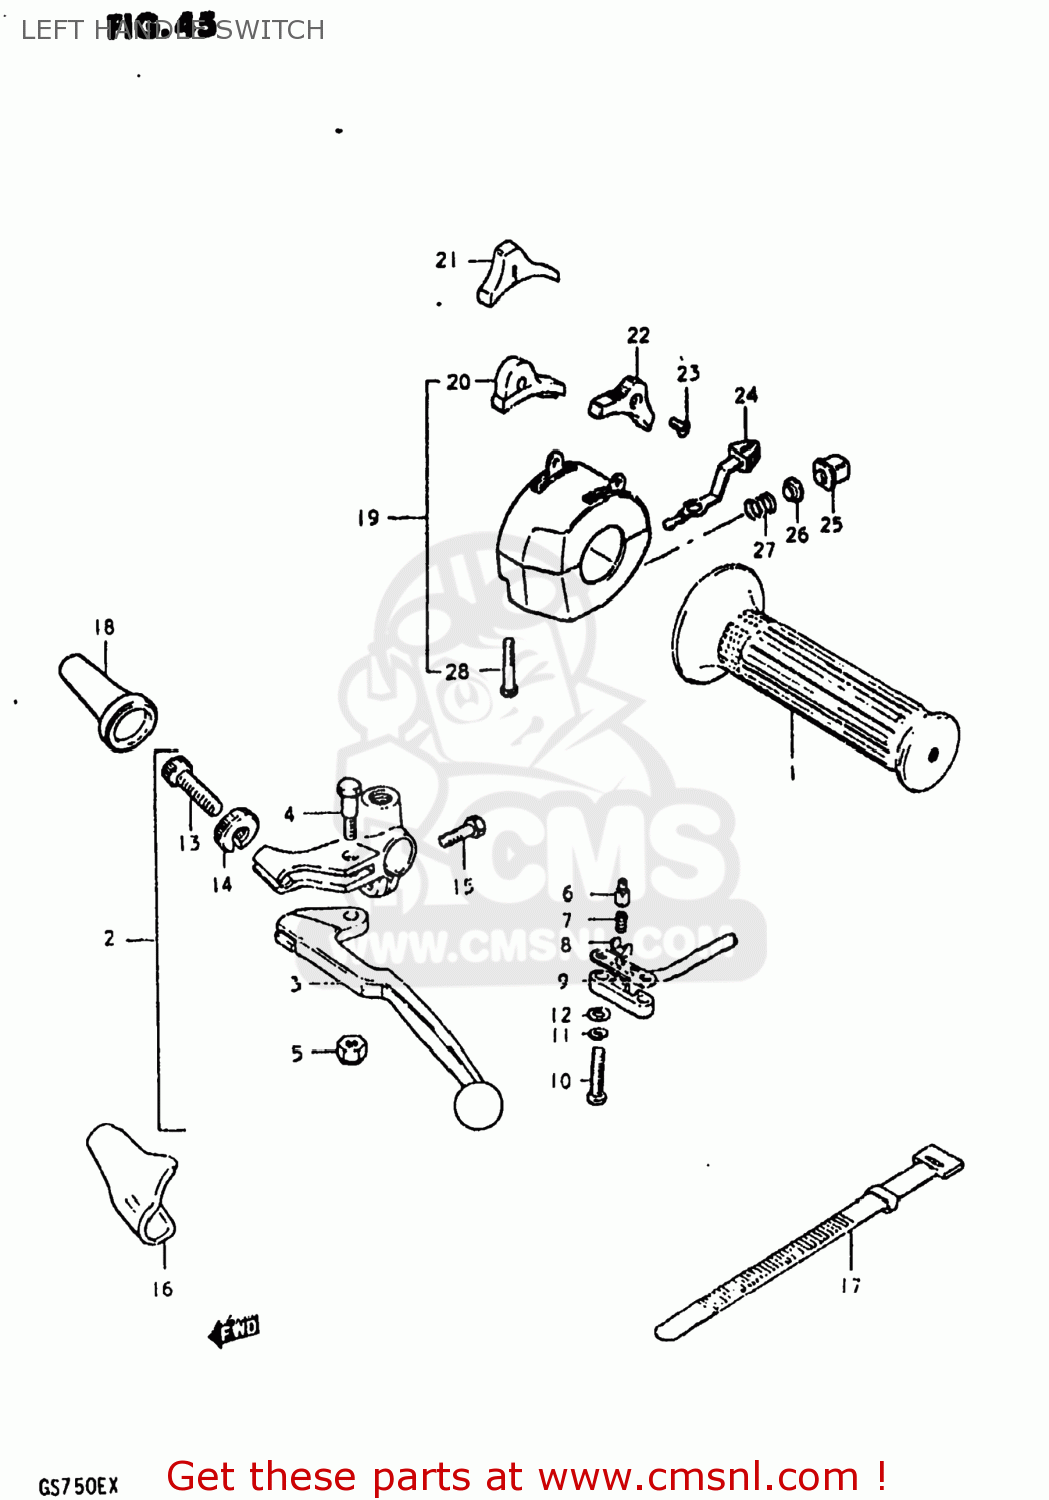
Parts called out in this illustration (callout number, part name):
1	GRIP,LEFT
2	LEVER ASSEMBLY
3	LEVER,CLUTCH
4	BOLT,LEVER
5	NUT 6MM
6	HOLDER
7	SPRING
8	PLATE
9	COVER,FR BK TERMINAL BASE
10	SCREW
11	LOCK WASHER
12	WASHER
13	ADJUSTER,CABLE
14	NUT,CABLE ADJUSTER
15	BOLT,CLUTCH LEVER HOLDER
16	COVER,CLUTCH LEVER
17	CLAMP(L:120)
18	BOOT,CLUTCH CABLE
19	SWITCH ASSY,HANDLE,L
20	KNOB,STOP
21	KNOB,LIGHTING SWITCH
22	KNOB,DIMMER SWITCH
23	SCREW
24	KNOB,TURNSIGNAL
25	BUTTON,HORN
26	SPRING
27	CONTACT
28	SCREW
